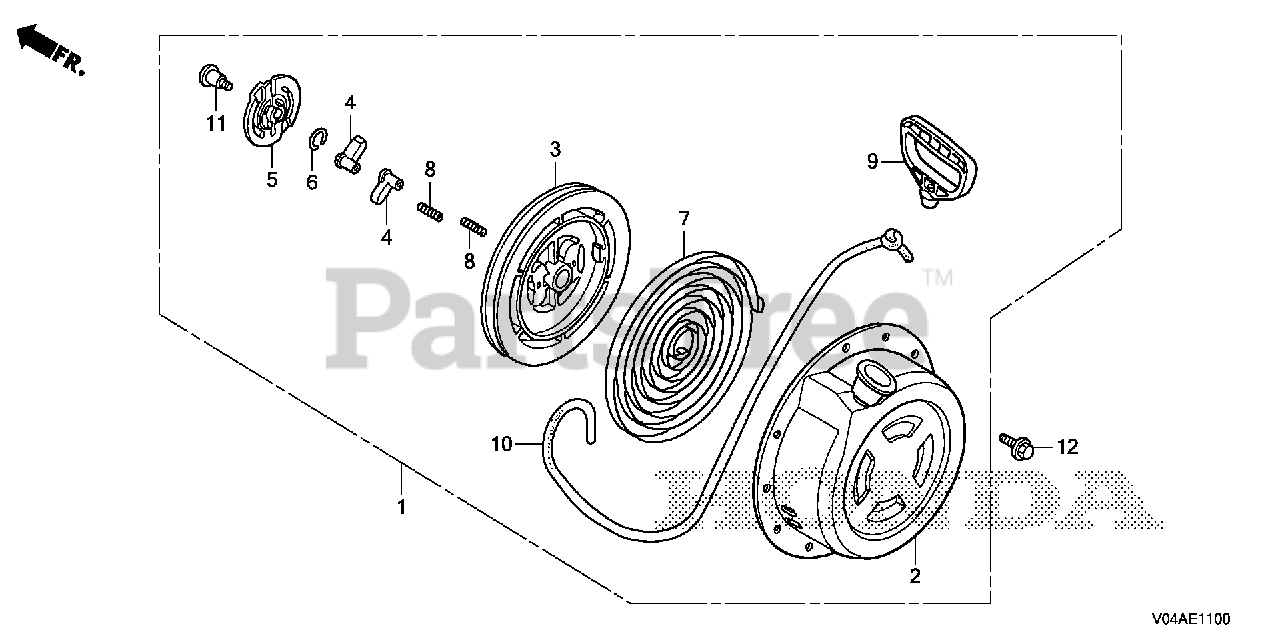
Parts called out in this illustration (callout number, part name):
1	STARTER ASSY., RECOIL *R280* (POWER RED)
2	CASE, STARTER *R280* (POWER RED)
3	REEL, RECOIL STARTER
4	RATCHET, STARTER
5	GUIDE, RATCHET
6	SPRING, FRICTION
7	SPRING, RECOIL STARTER
8	SPRING, RETURN
9	GRIP, STARTER
10	ROPE, RECOIL STARTER (NA USE ALT:08550-ZG921-11)
11	SCREW, SETTING
12	BOLT, FLANGE (6X10)
